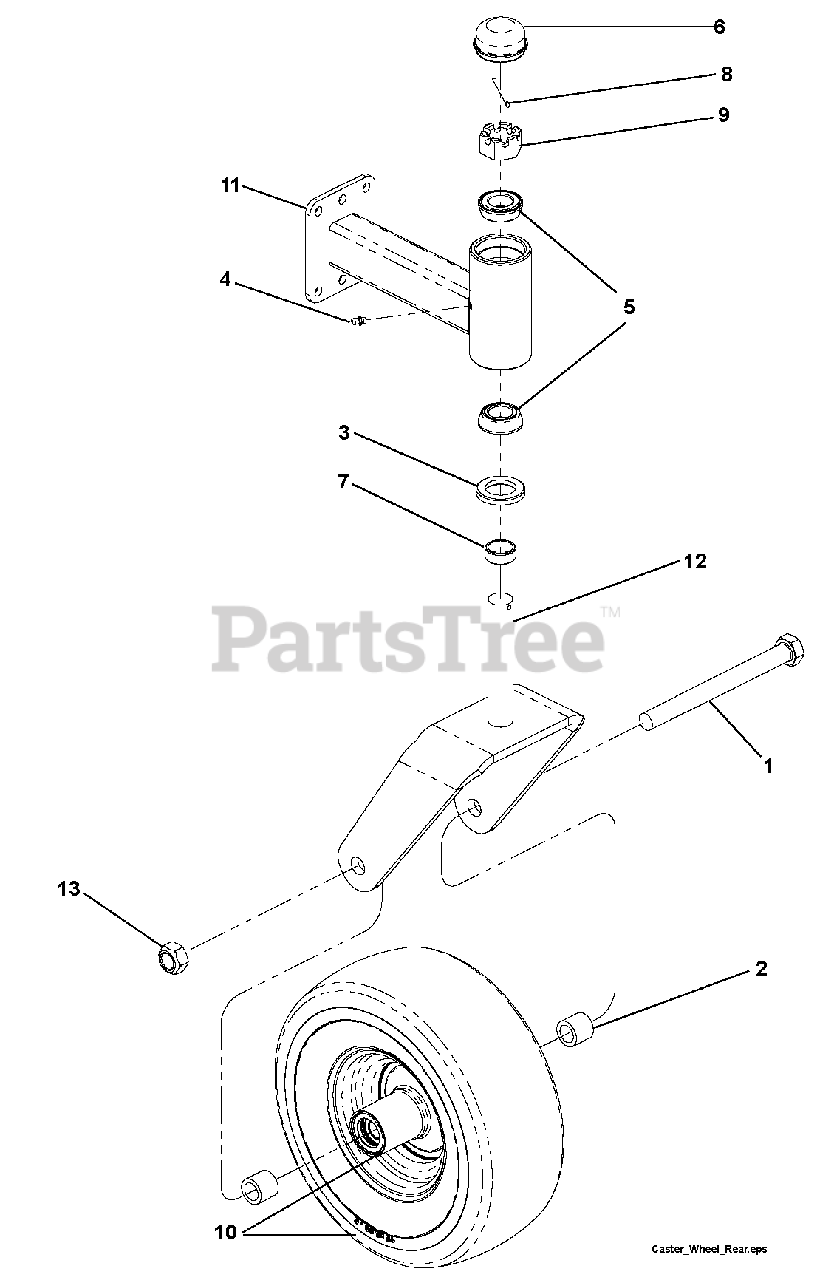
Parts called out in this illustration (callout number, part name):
1	Wheel Bolt, Caster
2	Spacer Assembly
3	Seal, Wheel Bearing
4	Fitting, Lubrication
5	Cone, Bearing
6	Cap, Dust
7	Spacer, Caster
8	Pin, Cotter, DIN94, 3.2 x 50-Steel-ZN
9	Nut, Hex Slotted 1-14 G5
10	Assembly, Caster Wheels and Tire
11	Weldment, Front Caster Support S/O
12	Weldment, Yoke
13	Locknut, 3/4-16 Crown GR 8
